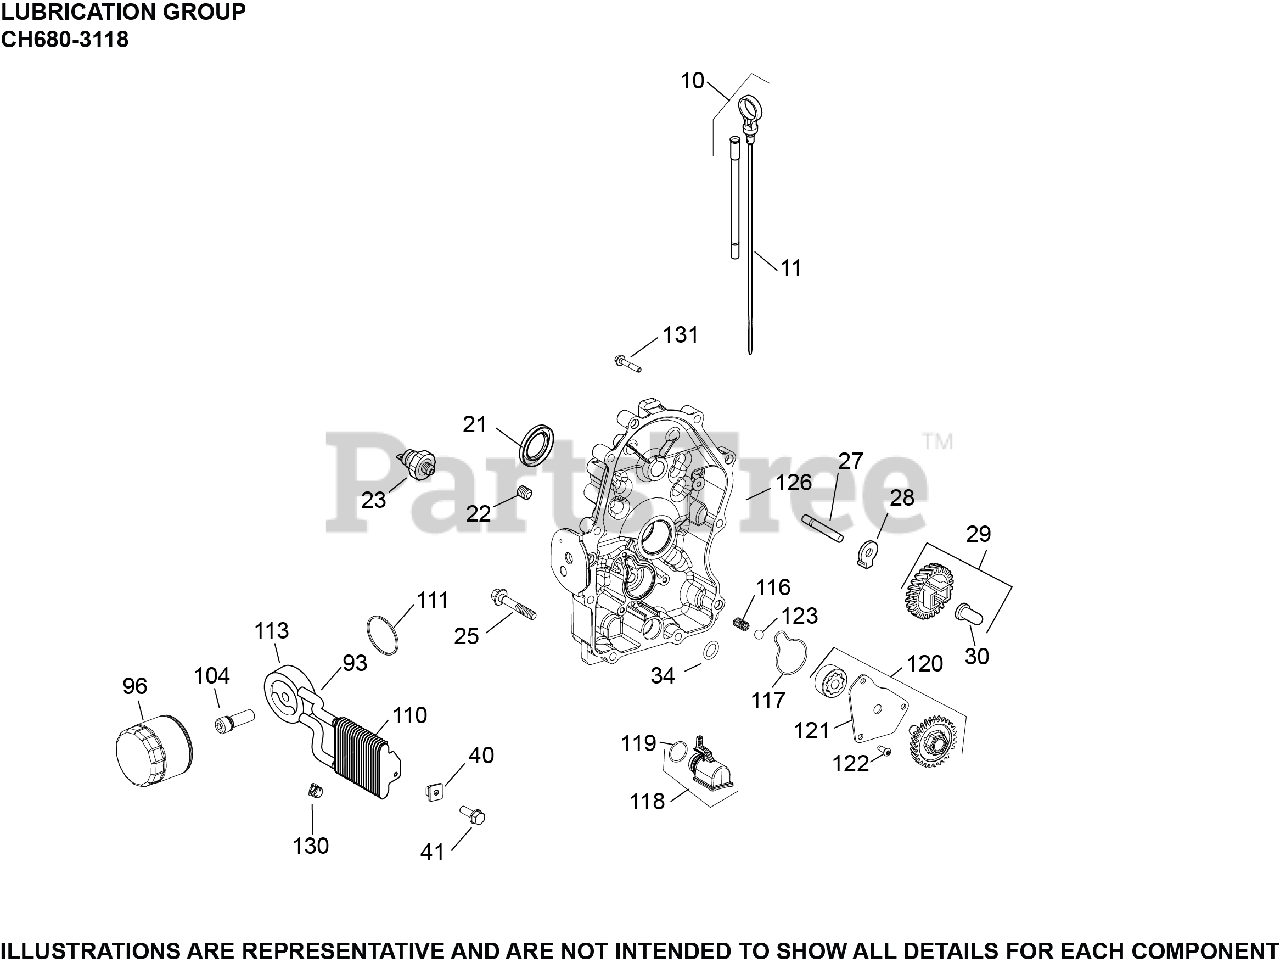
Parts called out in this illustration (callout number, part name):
10	KIT, DIPSTICK/DIPSTICK TUBES
21	SEAL, OIL
22	PLUG, CTSK PIPE 1/8"
23	SENSOR, OIL PSI
25	SCREW, FLG M8X1.25X45
27	SHAFT, GOVERNOR GEAR
28	TAB, LOCKING
29	KIT, GOVERNOR GEAR W/PIN
30	PIN, GOVERNOR REGULATING
40	NUT, PLASTIC - BLACK
41	SCREW, TAP M6X1.7X18
93	KIT, HOSE 140MM
96	OIL FILTER
104	NIPPLE, OIL FILTER
110	COOLER, OIL & DIVERTER ASSEMBLY
111	O-RING, OIL COOLER
113	ADAPTER, OIL FILTER (CV EFI)
116	SPRING, COMPRESSION
117	SEAL, OIL PUMP COVER
118	PICK-UP ASSEMBLY, OIL
119	O-RING, OIL PICK-UP
120	PUMP ASSEMBLY, OIL
121	COVER, OIL PUMP
122	SCREW, BUTTON HEAD
123	PRESSURE RELIEF BALL
126	KIT, CLOSURE PLATE
130	CLAMP, HOSE LOW PROFILE
131	SCREW, HEX FLANGE
